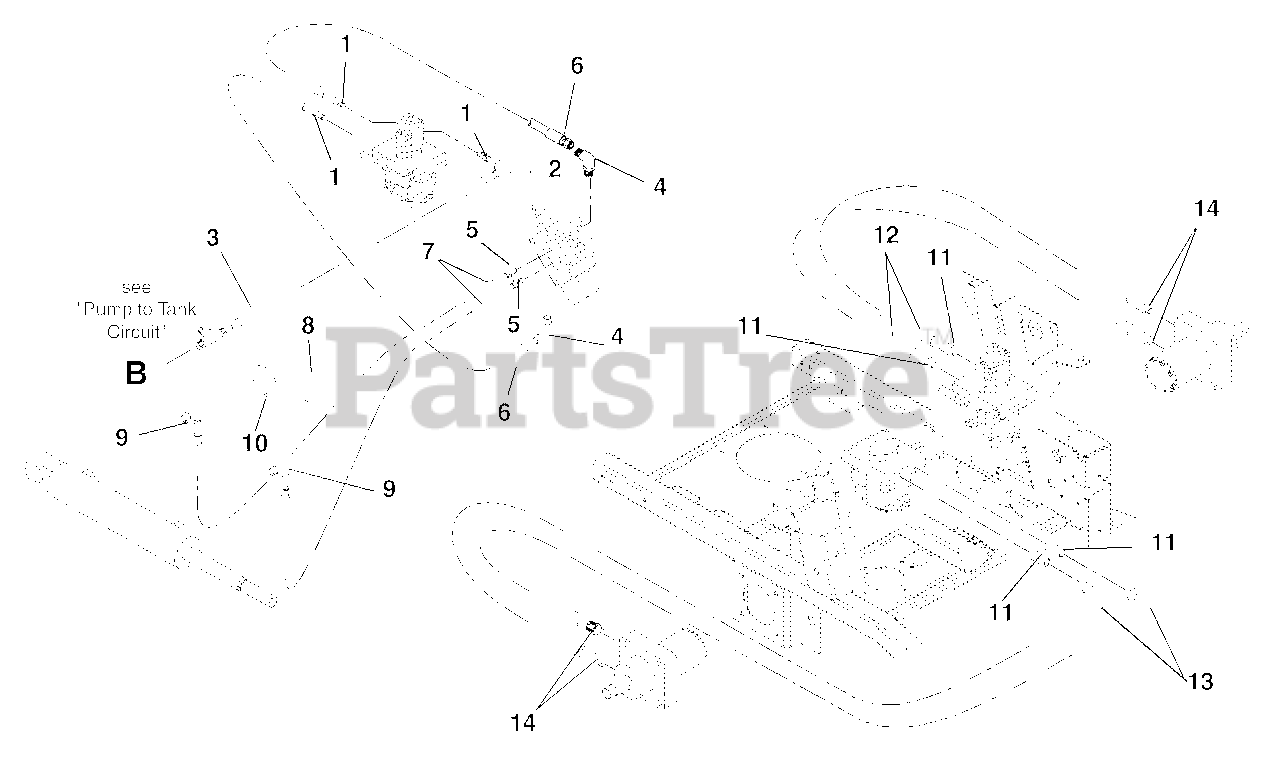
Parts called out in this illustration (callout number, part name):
2	Adapter
3	Hose-Hydraulic Valve to Tank
4	Adapter
5	Adapter
6	Hose Hydraulic .38 27.75 Long
7	Hose-Hydraulic .25 40.5" Long
8	Sleeve Protective 24"
9	Adapter
10	Cable Tie
11	Adapter-Hydraulic Steel .75 to .75
12	Hose-Hydraulic .50 18.75 Long
13	Hose-Hydraulic .50 x 29.50 Long
14	Adapter-Hydraulic Steel .875 to .75
